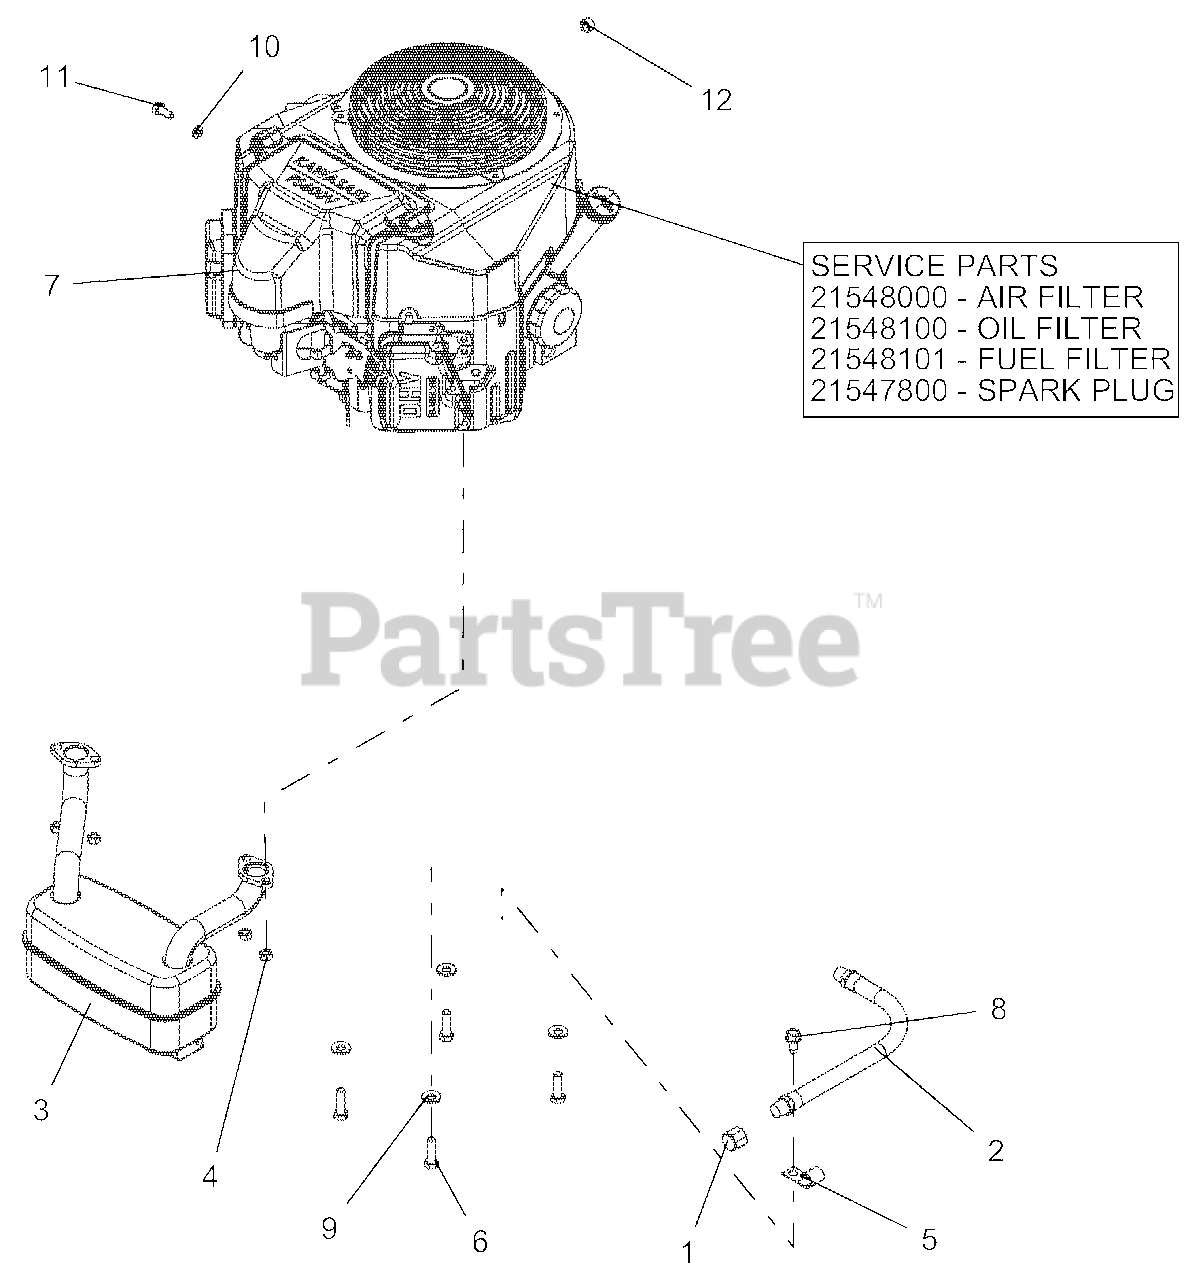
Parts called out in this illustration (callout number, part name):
1	PIPE, CAP 3/8 NPT FEMALE
2	HOSE, HYD .38-11-OK M6N0-M6N0
3	MUFFLER, KAWASAKI
4	NUT-LK-TOP M8-1.25 YWZC
6	BLT-HEX .38-16X1.25 GR5 YWZC NYTORQ
7	ENGINE, KAWASAKI FS730
7	AIR FILTER
7	OIL FILTER
7	FUEL FILTER
7	SPARK PLUG
8	SCR-TAP .38-16X.75 HWH TR YWZ
9	WSHR, 3/8" SPRING DISC
10	WSHR-LK .31X.078 REG YWZC
11	@BLT-HEX M8-1.25X20 YWZC
12	CLAMP, FUEL LINE
